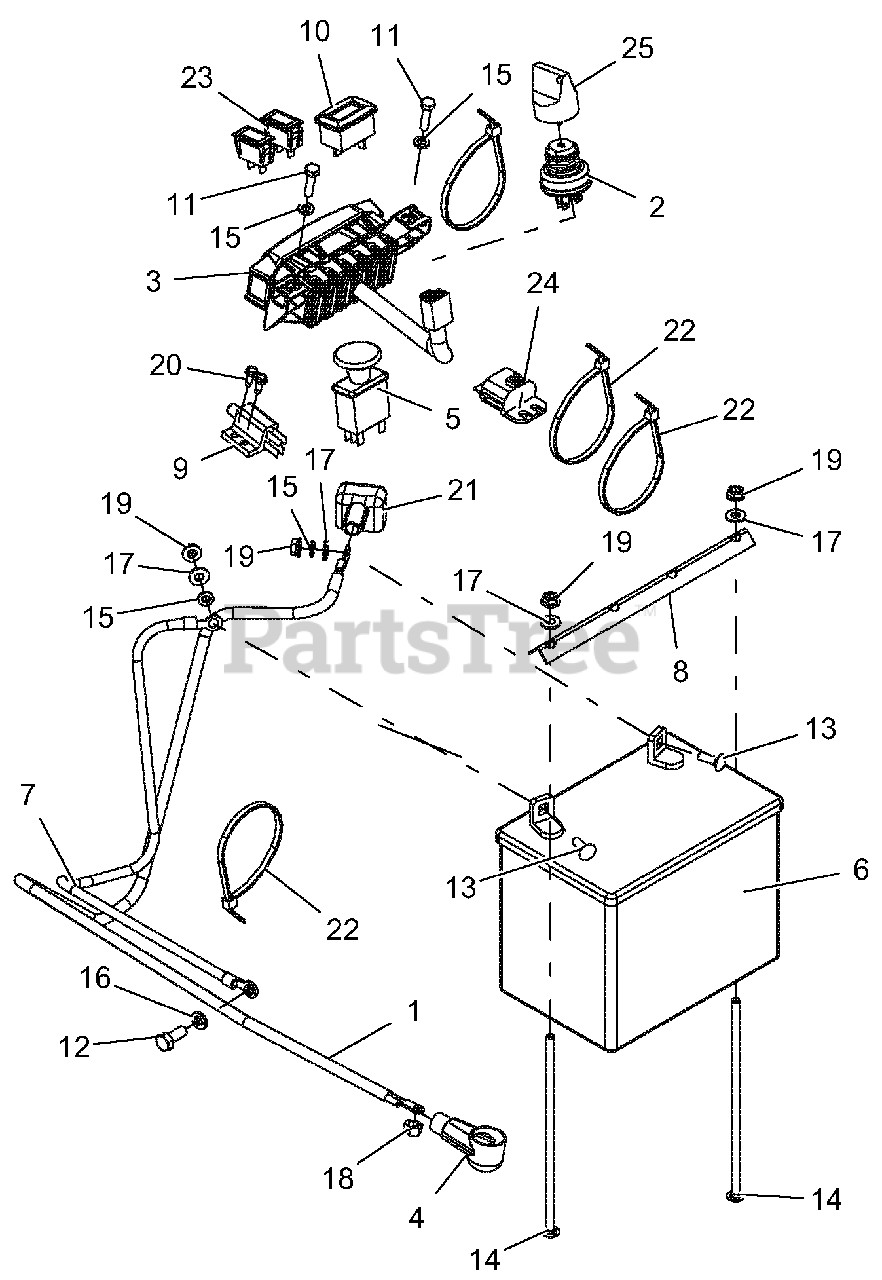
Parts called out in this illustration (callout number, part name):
1	CABLE, BATTERY - 42" POSITIVE
2	SWITCH, IGNITION
3	HARNESS, PROSTANCE WIRING
4	BOOT, BATTERY TERMINAL-RED
5	SWITCH, CLUTCH
6	BATTERY, 300 CCA 10U1L
7	CABLE, NEGATIVE BATTERY 35.00"
8	HOLD DOWN - BLK
9	SWITCH- DOUBLE POLE N.O./N.O.
10	METER, HOUR W/MAINTENANCE
11	@BLT-HEX M6-1.0X25 YWZC
12	@BLT-HEX M8-1.25X20 YWZC
13	BLT-RDHDSQNK .25-20X.75 G5 YWZC
14	BLT-RDHDSQNK .25-20X7.50 G2 YWZC
15	WSHR-LK .25X.062 REG YWZC
16	WSHR-LK .31X.078 REG YWZC
17	WSHR-FL-STL.281X.62X.065 YWZC
18	NUT-LK-TOP M8-1.25 YWZC
19	@NUT-SPNLK-FLG .25-20 YWZC
20	SCR-TAP 10-24X.50 HWH TR YWZC
21	INSULATOR
22	CABLE, TIE 5.50 LG
23	LIGHT, INDICATOR
24	MODULE, INTERLOCK
25	KEY, W/ COVER
